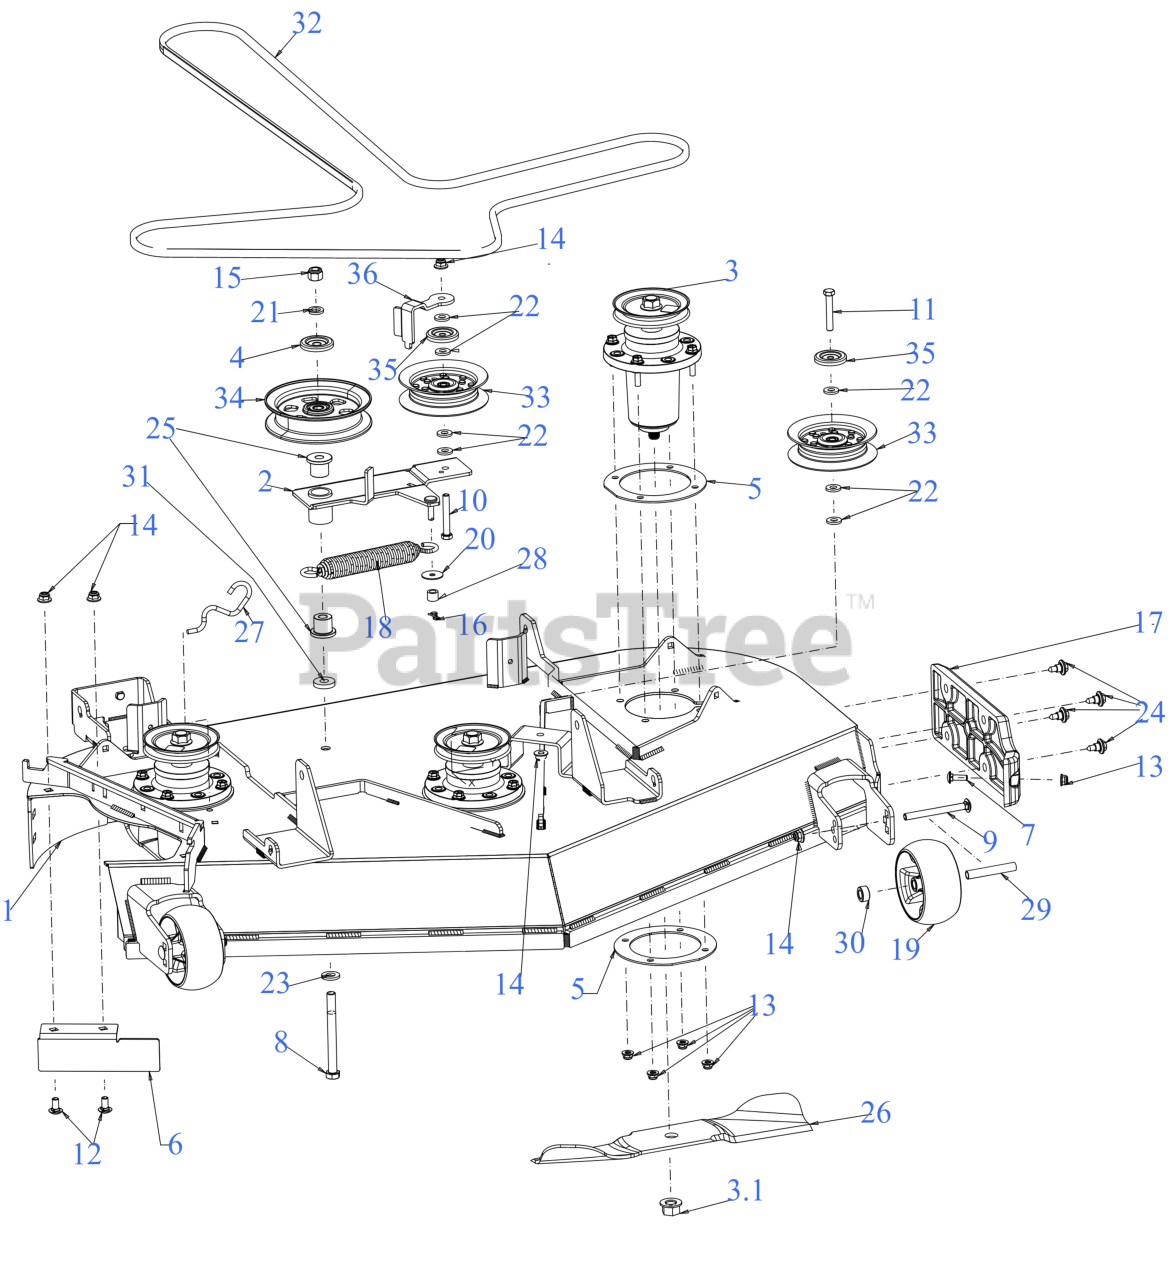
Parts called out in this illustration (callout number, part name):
1	48" FAB DECK SHELL
2	48" DECK IDLER ASSEMBLY
3	SPINDLE ASSEMBLY
3.1	FLANGE NUT - 5/8-18 GDE 8
4	PULLEY CAP
5	SPINDLE PLATE
6	48" DECK CHUTE BAFFLE
7	CARRIAGE BOLT 5/16-18 x 1.00
8	BOLT-HEX 1/2-13X5.0 GR5
9	CARRIAGE BOLT 3/8-16 x 4.00 GR5
10	HEX SCREW-3/8-16X2.5 GR5
11	SCREW 3/8-16 x 2.25 GR5
12	CARRIAGE BOLT 3/8-16 x .75
13	FLANGE LOCK NUT 5/16-18
15	HEX LOCK NUT NYLON
16	BOW TIE COTTER PIN 1/4-5/16
17	DECK SKID PLATE
18	SPRING 1.25" DIA x 8.5" LONG
19	DECK WHEEL
20	FLAT WASHER .322 ID x 1.25 x .060
21	LOCK WASHER 1/2
22	FLAT WASHER
23	FLAT WASHER .531X1.060X.134
24	SHOULDER SCREW .43X.29X5/16-18 TT
25	FLANGE BEARING
27	DECK SPRING HOOK
29	SPACER .38X.49X3.05LG
30	SPACER-.505 1D
31	SPACER PLATE
32	V-BELT (A SEC X 140.38)
33	IDLER PULLEY 4.0
34	5" FLAT IDLER PULLEY
35	IDLER PULLEY CAP
36	48" IDLER KEEPER
